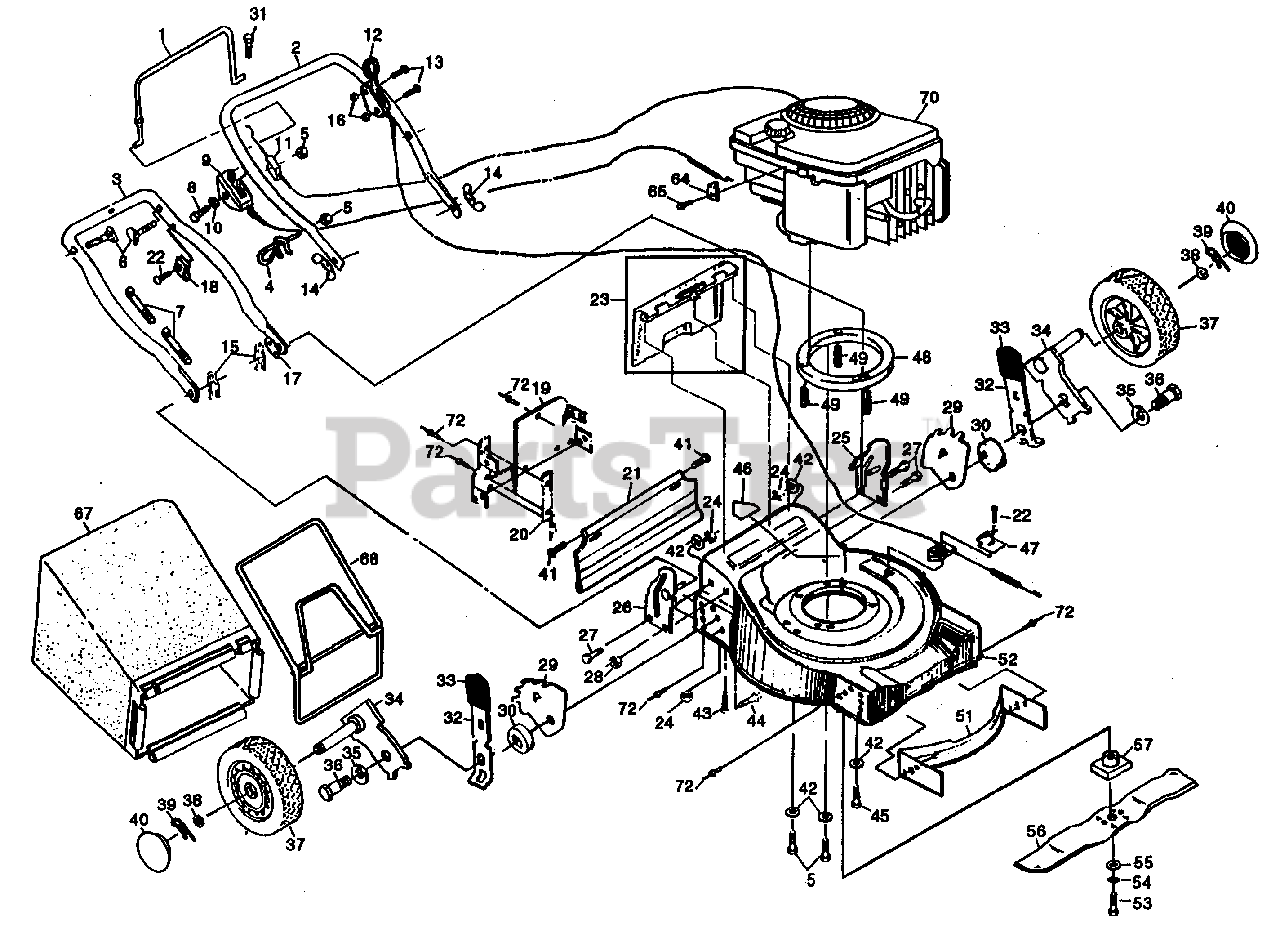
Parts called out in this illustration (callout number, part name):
1	Control Bar (AYP part number)
2	Upper Handle (AYP part number)
3	Lower Handle (AYP part number)
4	Rope Guide
5	Locknut 1/4-20 (AYP part number)
6	Handle Bolt (AYP part number)
7	Cable Tie (AYP part number)
8	Machine Screw 1/4-20 x 2 1/8 (AYP part number)
9	Throttle Control (AYP part number)
10	Washer (AYP part number)
11	Engine Zone Control Cable (AYP part number)
12	Drive Control
13	Pan Head Manchine Screw #10-24 x 2 (AYP part number)
14	Wing Nut (AYP part number)
15	Hairpin Cotter (AYP part number)
16	Locknut, #10-24 (AYP part number)
17	Cable Guide (AYP part number)
18	Cable Guide (AYP part number)
19	Back Plate (AYP part number)
20	Side Baffle (AYP part number)
21	Rear Skirt (AYP part number)
22	Self-Tapping Screw #10-24 x 3/4 (AYP part number)
23	Rear Door Assembly Kit (AYP part number)
24	Locknut 3/8-16 (AYP part number)
25	Handle Bracket Assembly (Left) (AYP part number)
26	Handle Bracket Assembly (Right) (AYP part number)
27	Screw 5/16-18 x 3/4 (AYP part number)
28	Locknut 5/16-18 (AYP part number)
29	Wheel Adjusting Bracket (AYP part number)
30	Spacer (AYP part number)
31	Self-Tapping Screw #10-24 x 5/8 (AYP part number)
32	Selector Spring (AYP part number)
33	Selector Knob (AYP part number)
34	Axle Arm Assembly (AYP part number)
35	Belleville Washer (AYP part number)
36	Shoulder Bolt 3/8-16 (AYP part number)
37	Wheel & Tire Assembly 8.0 x 1-3/4 (AYP part number)
38	Washer (AYP part number)
39	Retainer Clip (AYP part number)
40	Hubcap (AYP part number)
41	Hinge Screw (AYP part number)
42	Flat Washer (AYP part number)
43	Hex Tapping Screw 1/4-20 x 1/2 (AYP part number)
44	Hex Head Bolt 5/16-18 x 5/8 (AYP part number)
45	Hex Head Thread Rolling Screw 3/8-16x1 (AYP part number)
46	Danger Decal (AYP part number)
47	Bracket Cover (AYP part number)
48	Engine Spacer (AYP part number)
49	Engine Bushing (AYP part number)
50	Locknut (AYP part number)
51	Front Baffle (AYP part number)
52	Housing Assembly
53	Hex Head Bolt 3/8-24 x 1-3/8 Grd. 8
54	Helical Lock Washer (AYP part number)
55	Hardened Washer (AYP part number)
56	20" Blade
57	Blade Adapter
64	Cable Clamp (AYP part number)
65	Screw #10 x 5/8 (AYP part number)
67	Grass Bag (AYP part number)
68	Catcher Frame (AYP part number)
72	Pop Rivet (AYP part number)
